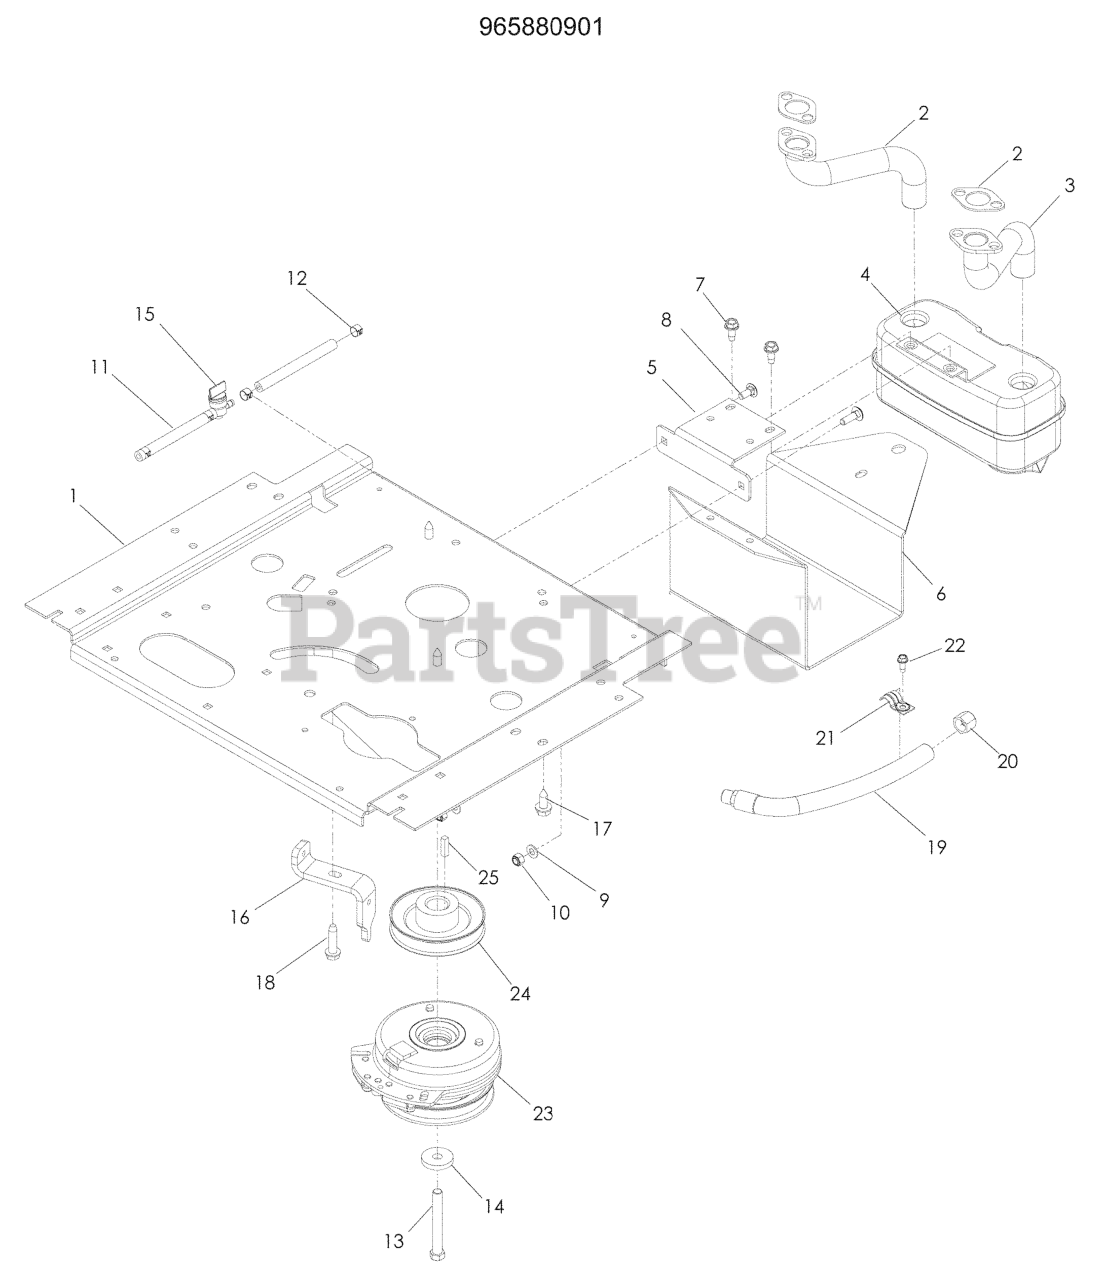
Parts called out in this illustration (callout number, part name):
1	PLATE, ENGINE, BLACK
2	RP.PIPE-EXHAUST LH
3	RP.PIPE-EXHAUST RH
4	MUFFLER ASM TWIN
5	BRACKET, MUFFLER, BLACK
6	GUARD, MUFFLER, BLACK
7	BOLT 5/16-18 X 3/4
8	BOLT 5/16C X 3/4" CARRIAGE
9	FLAT WASHER 5/16 SAE
10	NUT 5/16 NYLOC
11	FUEL LINE 5"
12	HOSE CLAMP
13	HCS 7/16-20X3-1/2 GR 5 ZN
14	CLUTCH, WASHER
15	FUEL VALVE
16	STOP, CLUTCH BLK
17	HHFS 3/8-16 X 1.0 THD FORMING
18	BOLT 3/8-16 X 1 1/2 ZINC CLEAR
19	OIL DRAIN HOSE
22	SCREW 1/4 X 5/8
23	CLUTCH, 105 FT-LBS
25	KEY 1/4 SQ X 1.0
26	WASHER 7/16 LOCK
27	EXHAUST GASKET - KAW
